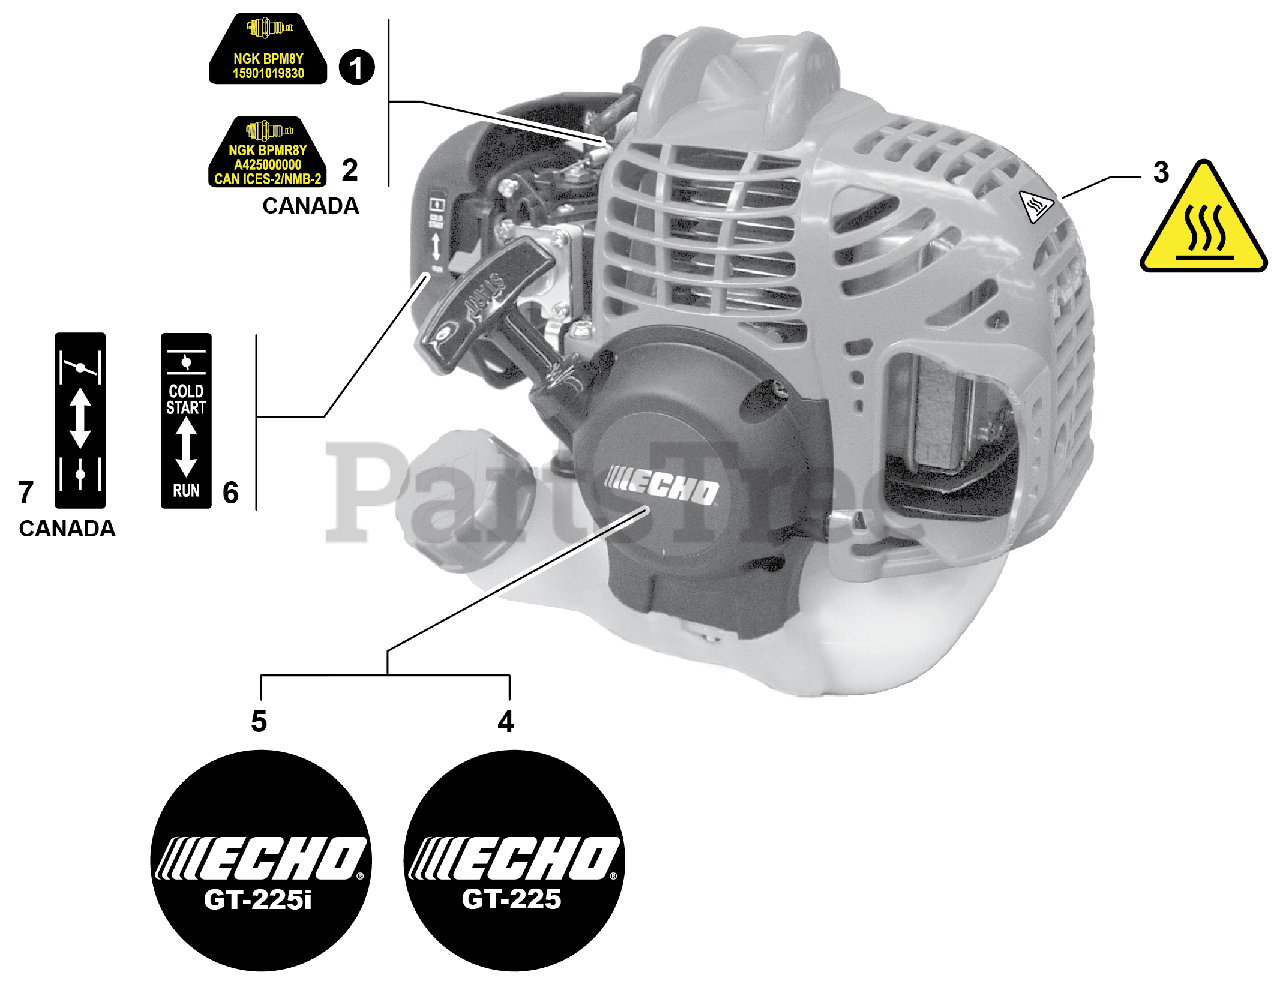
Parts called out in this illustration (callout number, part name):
1	LABEL, SPARK PLUG - BPM8Y
2	LABEL, SPARK PLUG - BPMR8Y
3	LABEL, CAUTION - HOT
4	LABEL, STARTER - GT-225
5	LABEL, STARTER - GT-225I
6	LABEL, CHOKE
7	LABEL, CHOKE
